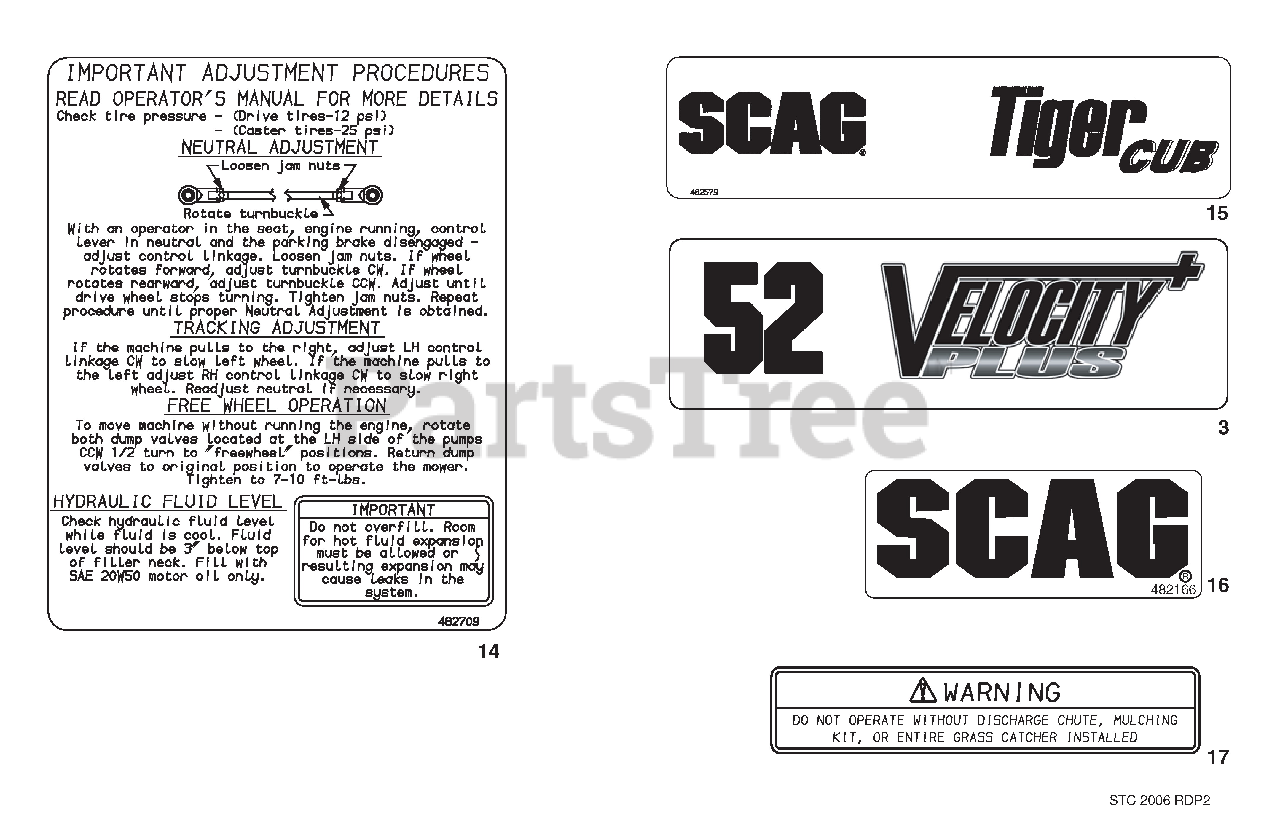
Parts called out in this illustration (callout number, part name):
3	Decal
14	Decal, Seat Support
15	Decal, Rear Bumper
16	Decal, Front Footplate
17	Decal, Discharge Chute
